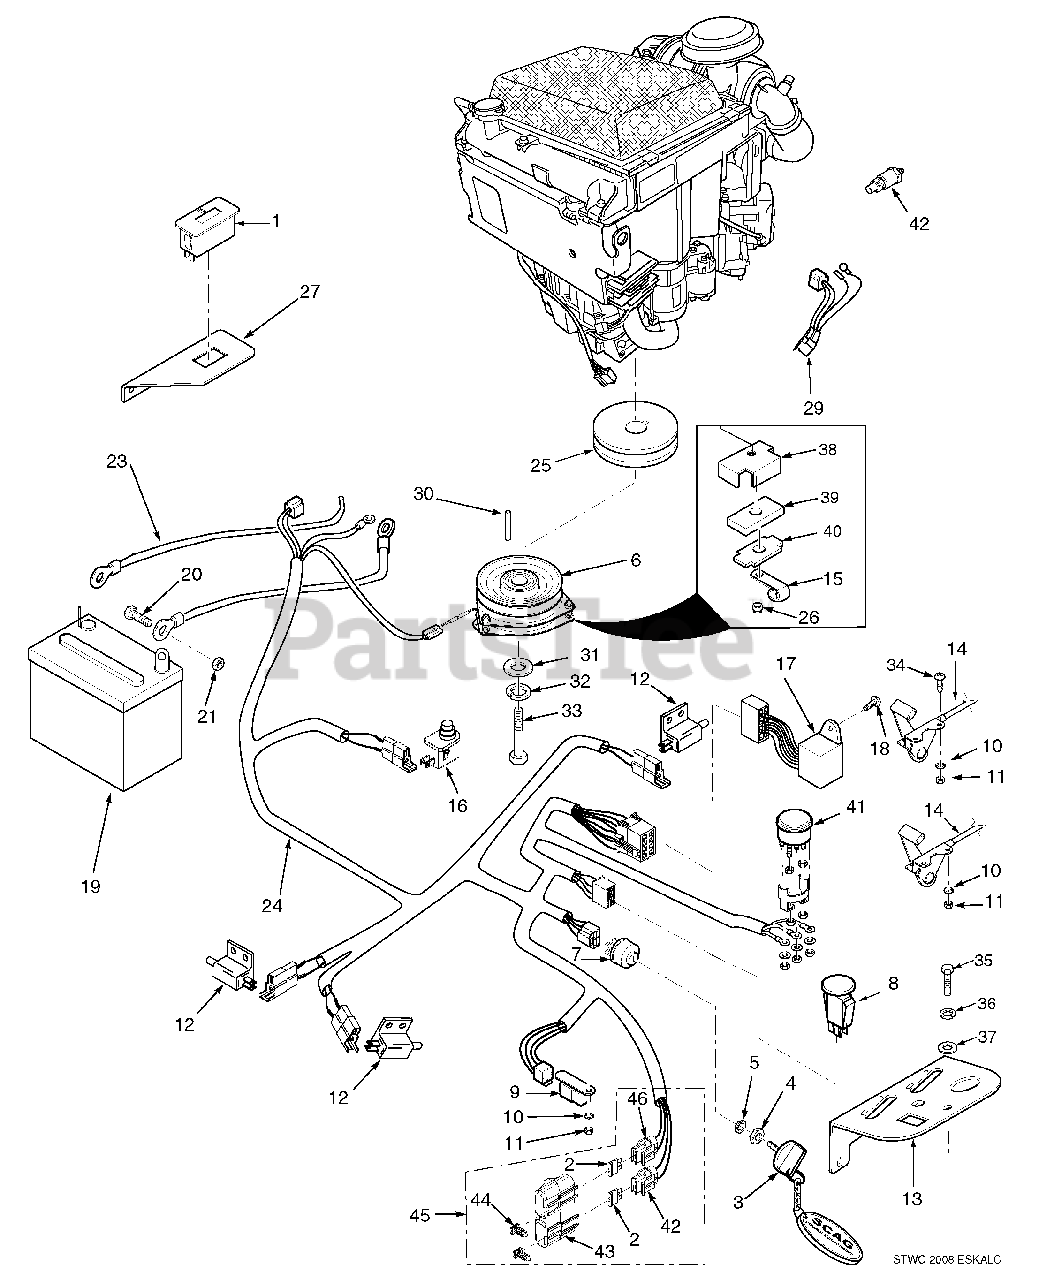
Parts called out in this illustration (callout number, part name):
1	Hourmeter
2	Fuse, 20 amp
3	Key, Ignition
4	Nut, Hex 5/8-32
5	Lockwasher, 5/8" Internal
6	Electric PTO Clutch GT3.5
7	Switch, Ignition
8	Switch, PTO
9	Relay
10	Lockwasher, #10 External Tooth
11	Nut, Hex #10-32
12	Switch, N/O
13	Panel, Instrument
14	Choke & Throttle Control
16	Switch, Seat
17	Module, Interlock
18	Screw, #10-32 x .5" Phillips Head
19	Battery
20	Bolt, Hex Hd. 1/4-20 x .5"
21	Nut, Hex 1/4-20
22	Cable, Battery Black (negative)
23	Cable, Battery Red (positive)
24	Wiring Harness, Main
25	Pulley, 5.45" OD x 1.125" Bore
26	Nut, Elastic Stop 5/16-18 Key
27	Mounting Bracket, Hour Meter
28	Screw, #10-32 x 1.5" Phillips Head
29	Adaptor, Wiring Harness
30	Key, 1/4 x 1/4 x 3-1/4"
31	Flatwasher, 7/16 (.469 x 1-3/4" x 1/4")
32	Lockwasher, 7/16"
33	Bolt, Hex Hd. 7/16-20 x 2-1/4" UNF
34	Screw, #10-32 x 3/4"
35	Bolt, Hex Hd. 5/16-18 x 3/4"
36	Lockwasher, 5/16"
37	Flatwasher, 5/16 (.375 x .875 x .083")
38	Backing Plate
39	Rubber Pad, Clutch Stop
40	Plate, Backing
41	Water Temp. Gauge
42	Sender Unit, Water Temp
43	Cover, Sealed Double
44	Clip, Wire
45	Double Fuse Assembly, Sealed
46	Fuse Holder
